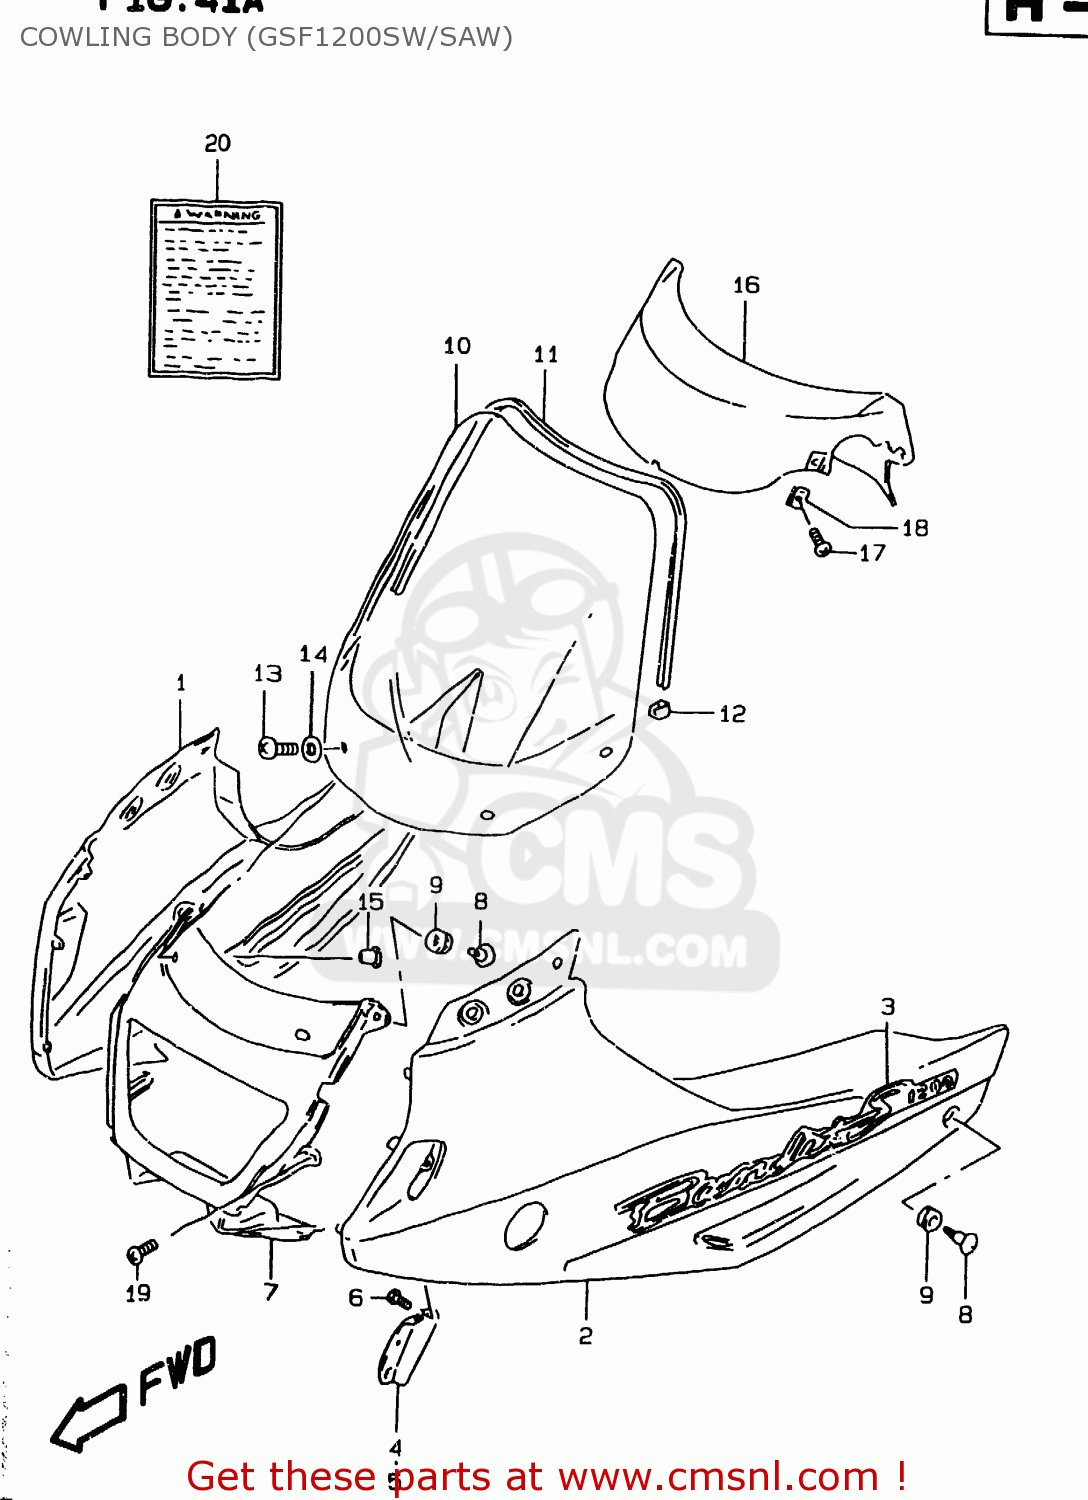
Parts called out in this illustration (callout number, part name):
1	COWLING ASSY,SIDE,R
2	COWLING ASSY,SIDE,L
3	EMBLEM,COWLING SIDE
4	COVER,COWLING INNER,R
5	COVER,COWLING INNER,L
6	SCREW 5X10
7	COWLING ASSY,CTR
8	SCREW(6X20)
9	CUSHION
10	WINDSCREEN SET
11	MOLDING WINDSCREEN
12	CLIP,WINDSCREEN MOLDING
13	SCREW(5X14)
14	WASHER
15	NUT
16	PANEL,INNER
17	SCREW
18	NUT
19	SCREW
20	LABEL (WARNING SCREEN)
